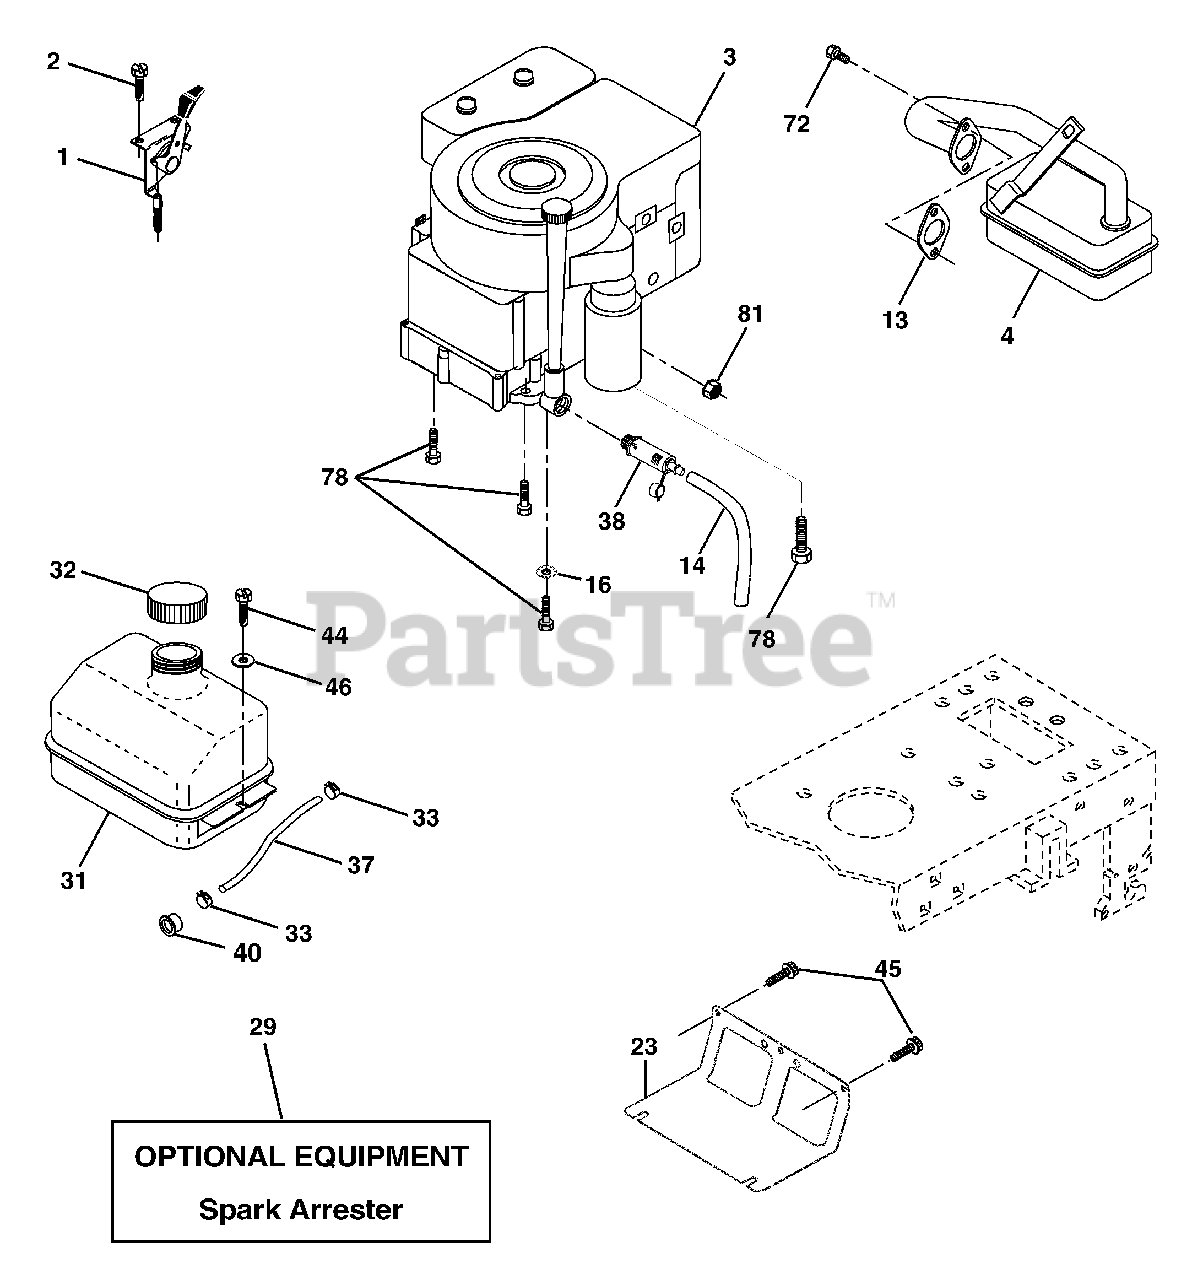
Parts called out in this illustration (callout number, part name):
1	Control Throt /Ch Flag
2	Screw Hex Thd Cut 1/4-20 x 1/2
4	Muffler Exhaust B&S Lt
13	Gasket 1 313 Id Tin Plated
14	Tube Drain Oil Easy
16	Washer Lock Ext Tooth 3/8
23	Shield Browning/Debris Guard
29	Arrestor Spark
31	Tank Fuel 1 25 Fr
32	Cap Asm Fuel W/sym Vented
33	Clamp Hose Blk
37	Line Fuel 20"
38	Plug Drain Oil Easy
40	Bushing Snap Nyl Blk Fuel Line
44	Screw Hexwsh Thdrol 1/4-20 x 3/4
45	Screw Hex Wsh Thdrol 3/8-16
46	Washer 9/32 x 7/8 x 16ga
72	Screw Socket Head 5/16-18 x 1
78	Screw Thdrol 3/8-16 x 1-1/4
81	Nut Keps Hex 1/4-20 Unc
